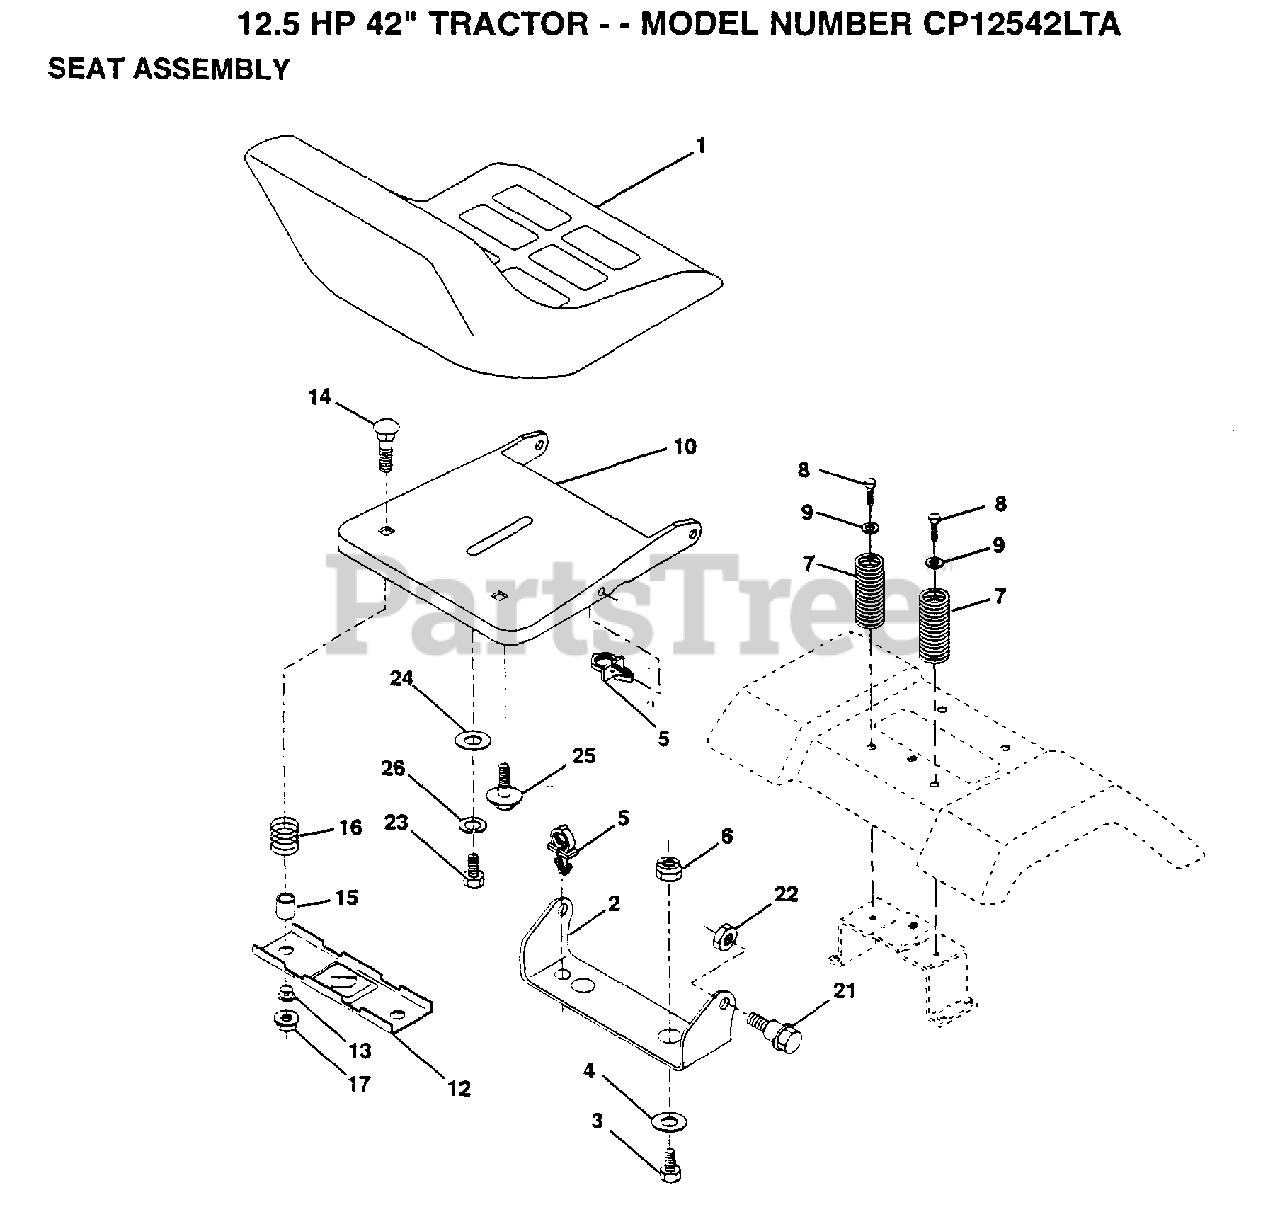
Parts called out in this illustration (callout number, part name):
2	BRACKET PVT SEAT
3	BOLT
4	WASHER PM
5	CLIP PUSH - IN
6	NUT
7	SPRING COMPRESSIO
8	SCREW GTV
9	WASHER
12	BRKT SWITCH
13	BUSHING
15	SPLIT SPACER
16	SPRING
21	BOLT.SHLD.5/16-18
22	NUT
23	BOLT
24	WASHER
25	"BOLT,SHOULDER"
26	LOCKWASHER
